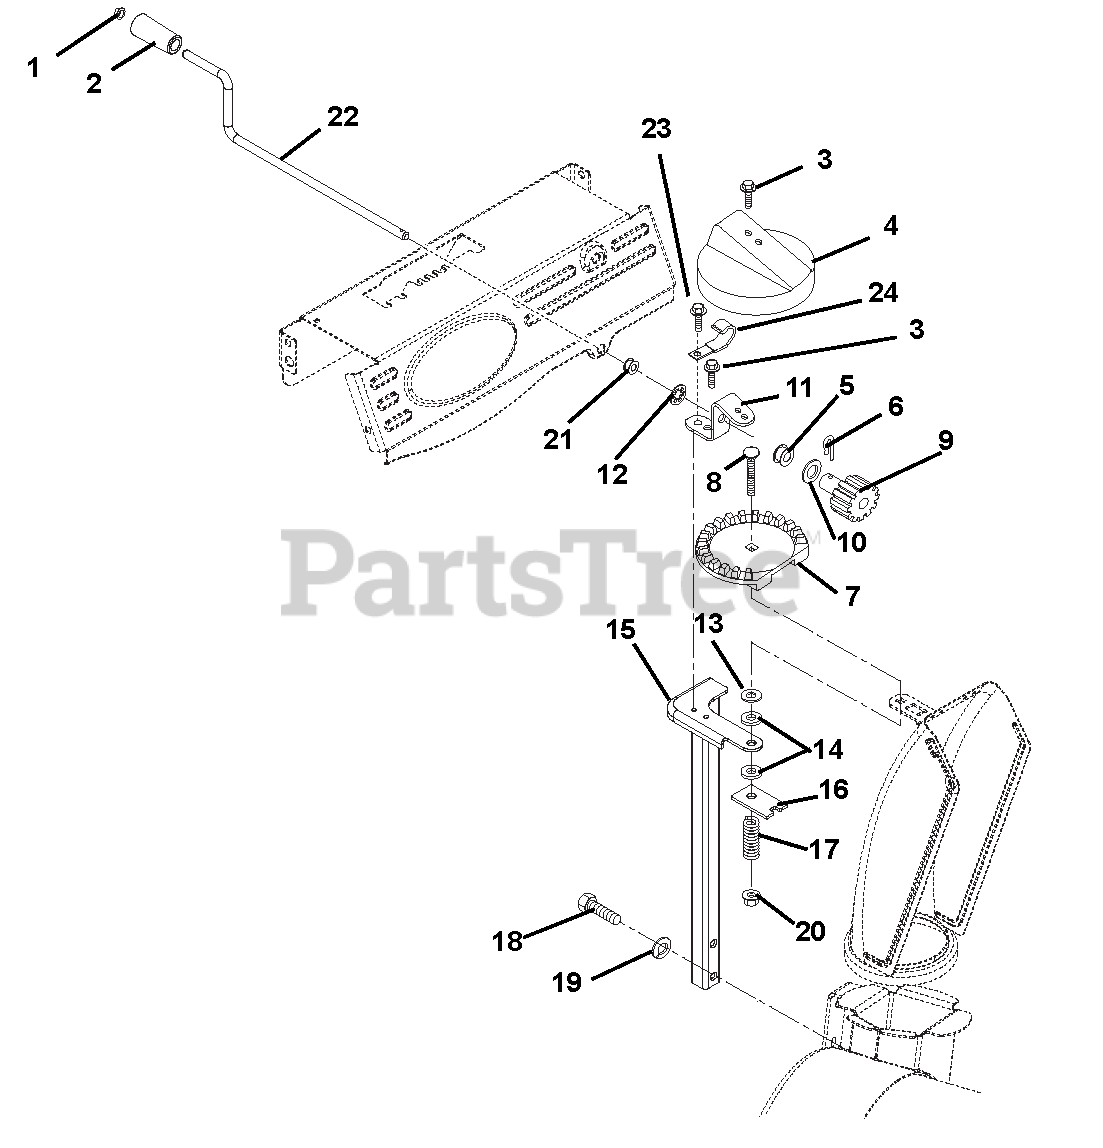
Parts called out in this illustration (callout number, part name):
1	CAP, 3/8 ROD YWZC
2	KNOB, CHUTE CRANK
3	SCR-TAP .25-20X.50 HWH TR YWZ
4	GEAR COVER
5	BUSHING, POLYLINER-.63 SNAPIN
6	PIN, SPRING CLIP
7	CHUTE GEAR
8	@BLT-RDHDSQNK .38-16X2.50 G5YZ
9	PINION GEAR W/BRACKET
10	WSHR-THRST .625 X 1.0 X .03
11	BRACKET, PINION GEAR
12	PUSHNUT .625
13	WSHR-FL-STL .380X1.50X.062 YWZ
14	FRICTION WASHER
15	CHUTE PEDESTAL, TALL COMPACT
16	PLATE, FRICTION
17	SG-COMP .187X.56X1.62
18	@BLT-HEX .38-16X1.75 GR5 YWZC
19	@WSHR-LK .38X.094 REG YWZC
20	@NUT-LK-TOP-FLG .38-16 YWZC
21	BUSHING, POLYLINER-.38 SNAPIN
22	CHUTE CRANK,COMPACT 920,XXX HI
23	SCR-TAP .25-20X.50 HWH TR YWZ
23	SCR-TAP .25-20X.50 LGHWH TR YZ
24	J-CLAMP
